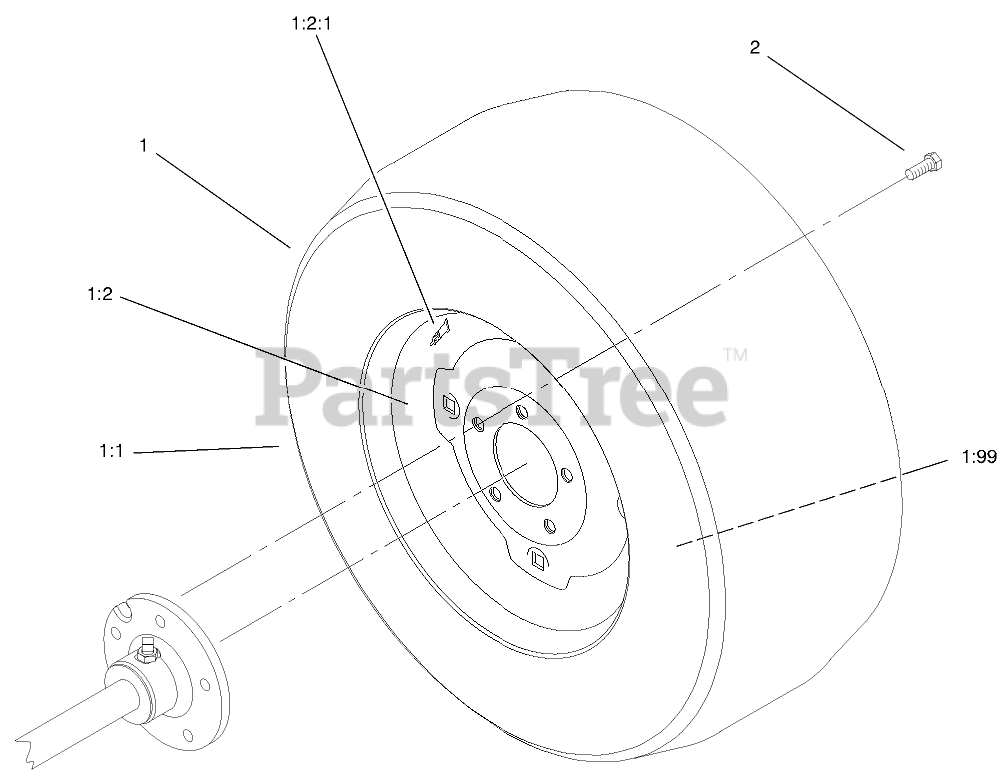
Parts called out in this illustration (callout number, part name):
1	Wheel & Tire ASM
1:2	RIM ASM
1:2:1	VALVE
1:99	TUBE-INNER
2	BOLT-LUG
